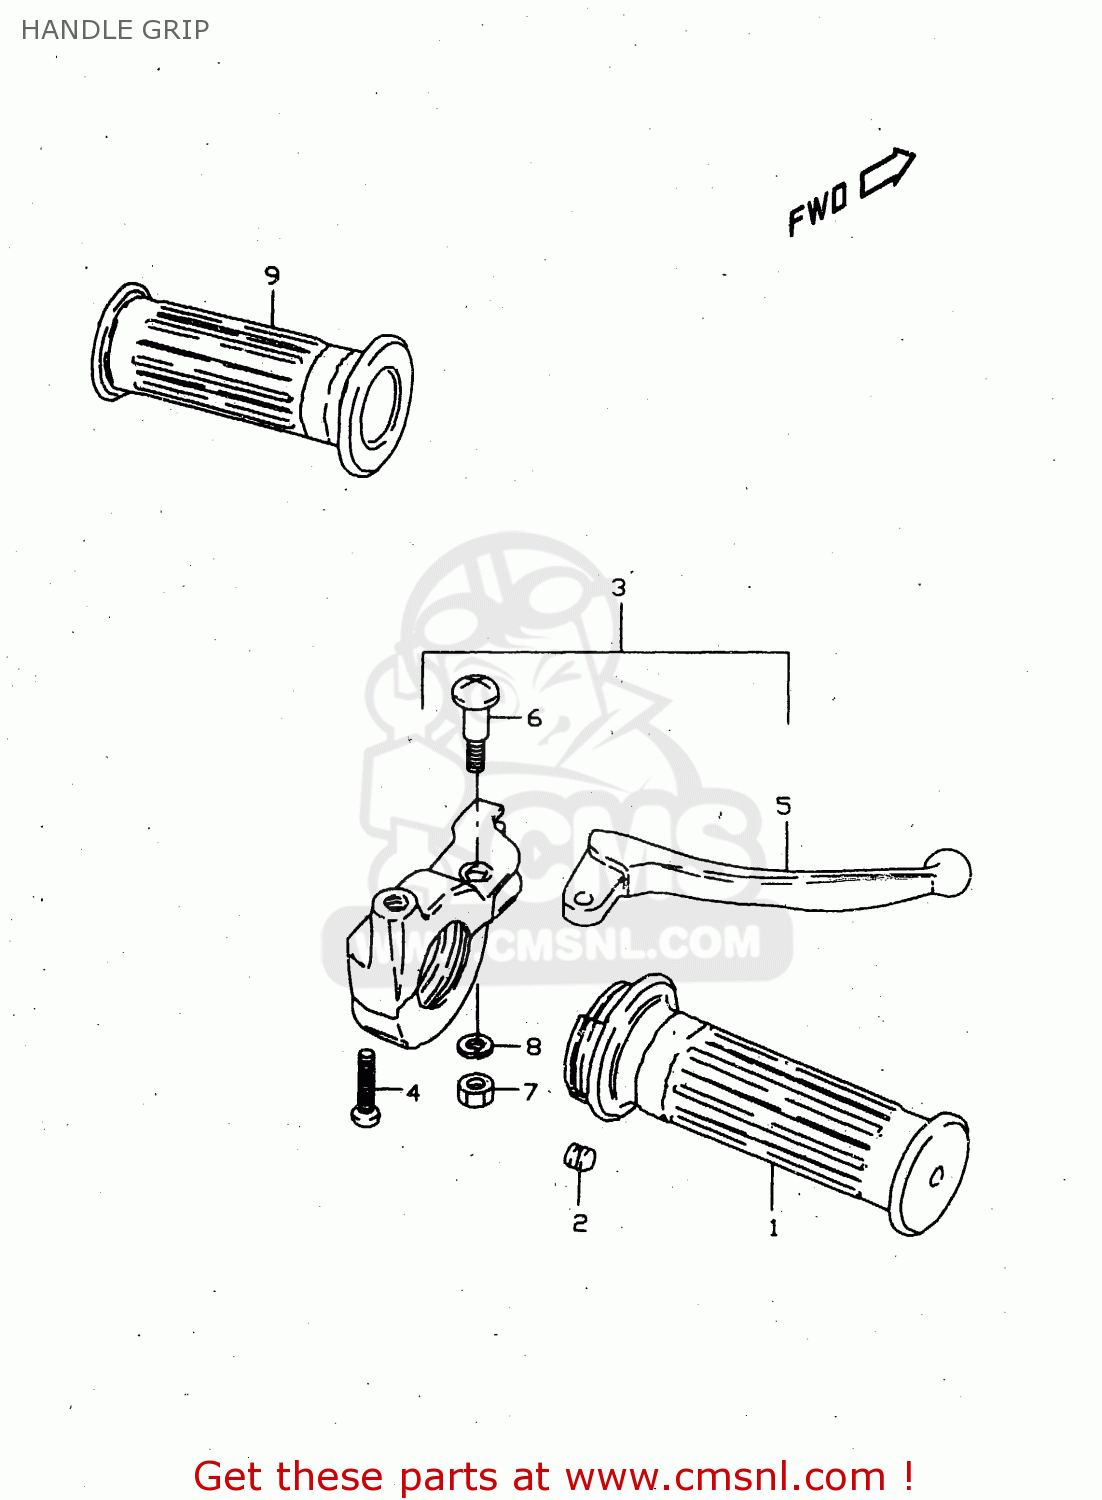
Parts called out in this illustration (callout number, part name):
1	GRIP,THROTTLE
2	PIECE,THROTTLE END
3	LEVER ASSY,BRAKE
4	SCREW(5X22)
5	LEVER,BRAKE
6	SCREW,BRAKE LEVER PIVOT
7	NUT
8	LOCK,WASHER
9	GRIP,L
